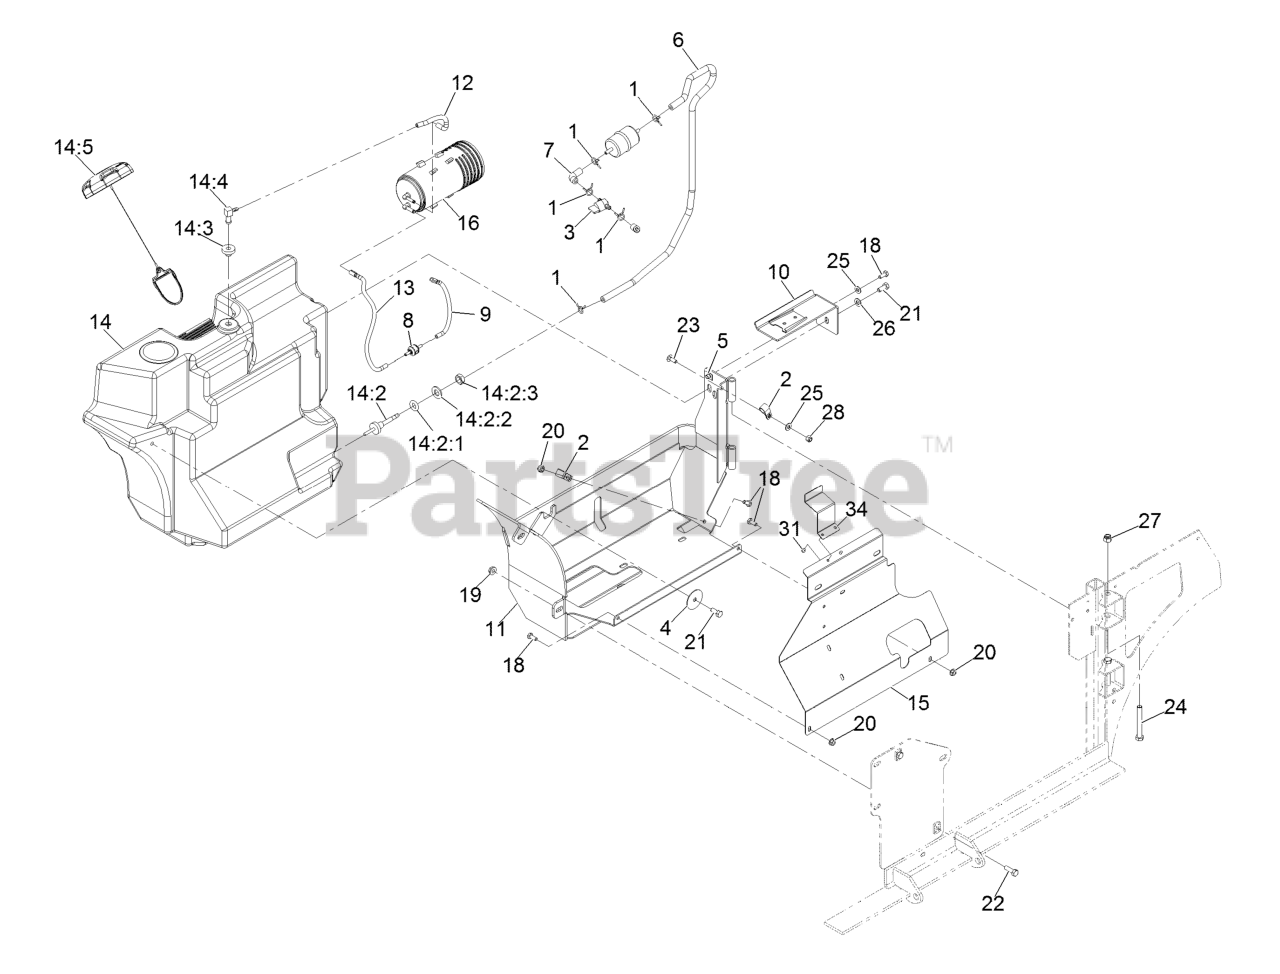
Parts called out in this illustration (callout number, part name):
2	CLIP-LOOM
3	VALVE-FUEL
5	Nut-Retainer-Panel 1/4-20
6	HOSE-FUEL
7	HOSE-FUEL
9	HOSE-VENT, FORMED
10	CANISTER BRACKET ASM
11	TANK FRAME ASM
12	HOSE-VENT, FORMED
13	HOSE-VENT, FORMED
14	FUEL TANK ASM
14:2	FITTING-FUEL, BULKHEAD
14:2:1	O-RING,BULKHEAD FITTING
14:2:2	WASHER-FLAT
14:2:3	NUT-JAM
14:3	BUSHING
15	PANEL-TANK SHIELD
16	CANISTER-CARBON, 800CC
18	SCREW-HH
21	SCREW-HH
22	SCREW-HH
23	BOLT-CARR
24	SCREW-CARR
25	WASHER-FLAT
26	WASHER-PLAIN
27	NUT-LOCK, NI
28	NUT-LOCK, NI
31	RIVET-POP
34	BRACKET-SHIELD, TANK
